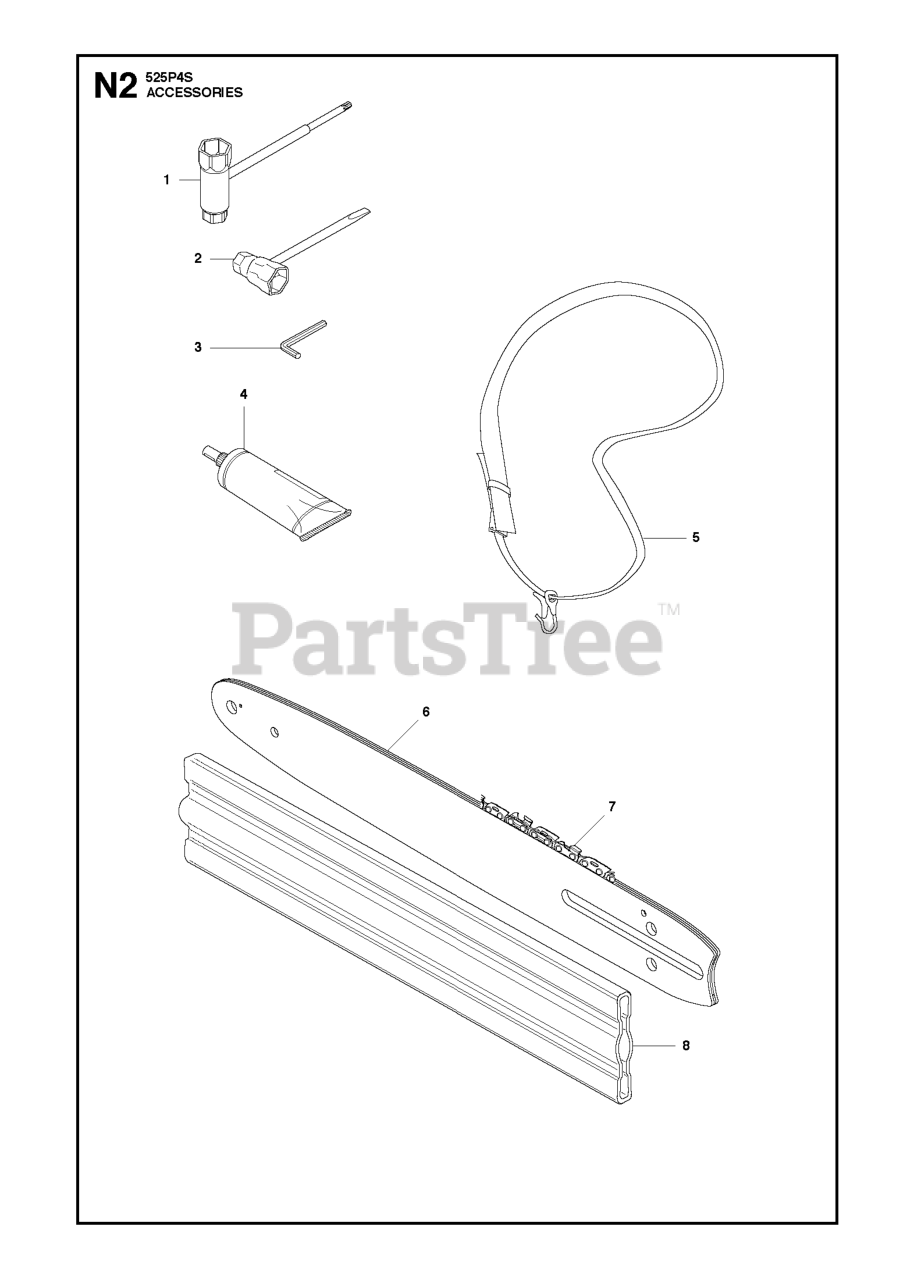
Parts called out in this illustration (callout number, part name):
1	COMBINATION WRENCH TORX
2	COMBI TOOL
4	GREASE
5	Harness-w/o warning
6	Hl280-40 Guide Bar
6	Hl280-45 Guide Bar
7	10" CHN, H37-40 3/8,.050 MINI
7	RP12" CHN,H37-45 3/8,.050 MINI
